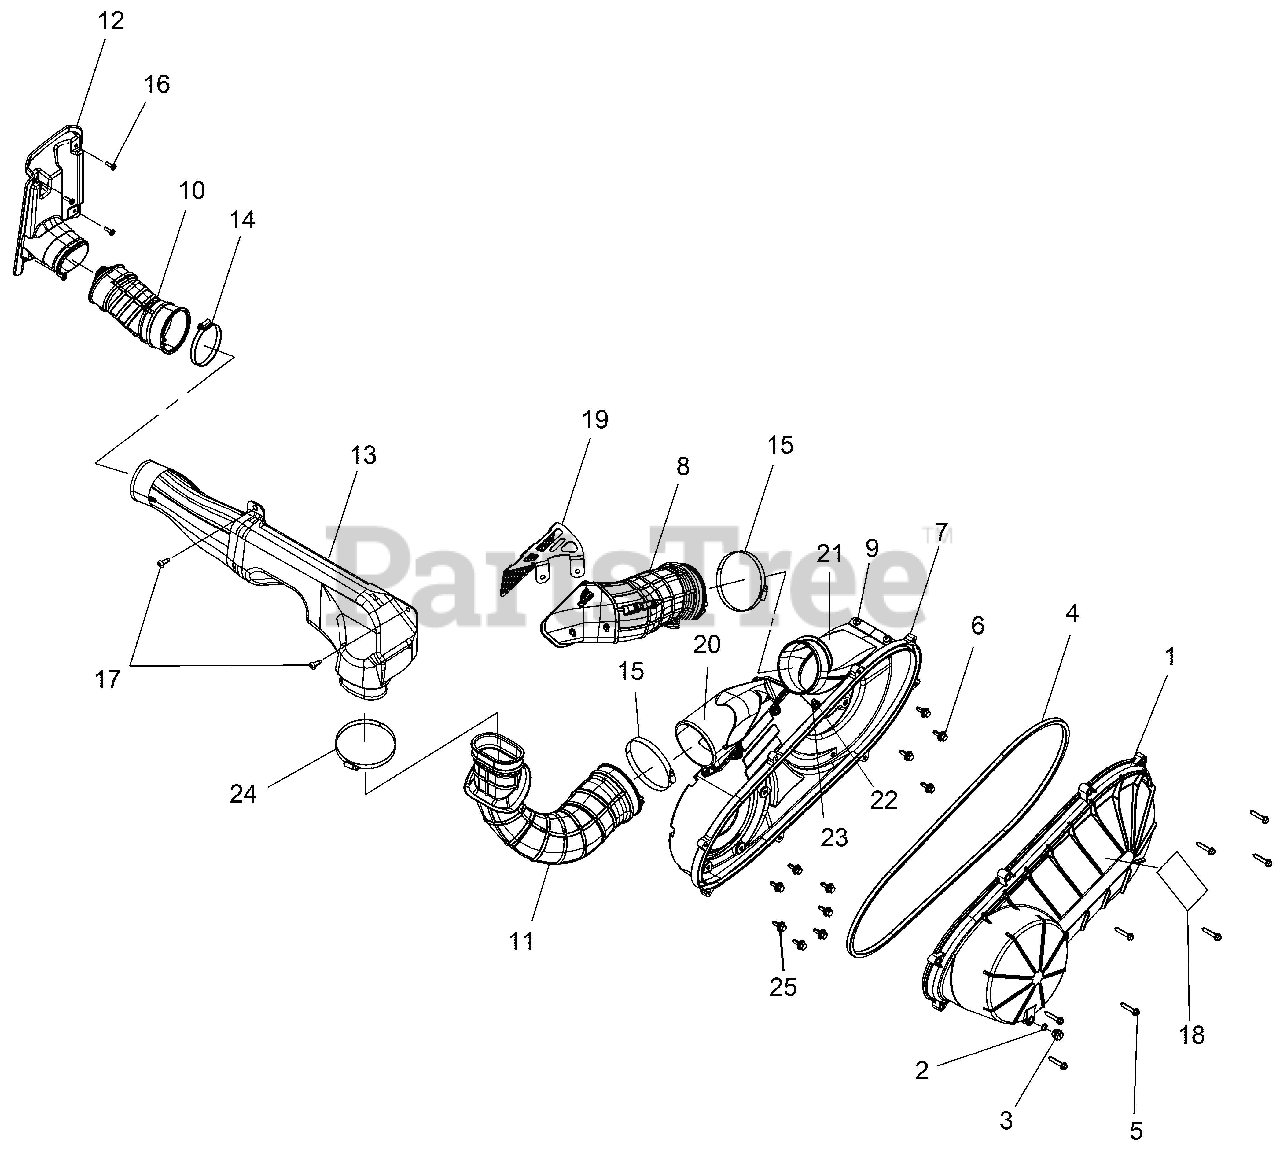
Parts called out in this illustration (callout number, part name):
1	ASM-COVER,CLUTCH,OUTER DSL
2	O RING (10)
3	PLUG-DRAIN
4	SEAL-OUTER CLUTCH COVER
5	SCR-HXFL-M6X35 ZOD HILO
6	ASM-BOLT/WASHER,20 MM
7	ASM-COVER,CLUTCH,INNER DSL
8	HOSE, CLUTCH, AIR OUTLET
9	SCR-#14X3/4 HI/LO-PH-PN TRX-M
10	HOSE-INTAKE,CLUTCH
11	HOSE-CLUTCH,AIR INLET
12	INTAKE-FENDER-REAR
13	DUCT-INTAKE,CLUTCH
14	CLAMP,BAND,NARROW (10)
15	CLAMP-WORM DRIVE,3.69 DIA
16	SCR-10X5/8-HI/LO,PN-T25,TRX-M
17	SCR-TX TRUSS-#14X3/4,HI/LO ZBK
18	DECAL, BELT, CAUTION/CHECK
19	BRKT-SCREEN,BELT
20	DUCT-CLUTCH,AIR INLET
21	DUCT, AIR OUTLET
22	SCR-M6X1.0X20MM,TX,PH,8.8-B
23	NUT-HXFL-M6X1.0 8 ZB3 NYL
24	CLAMP-BAND,NARROW 70-90MM
